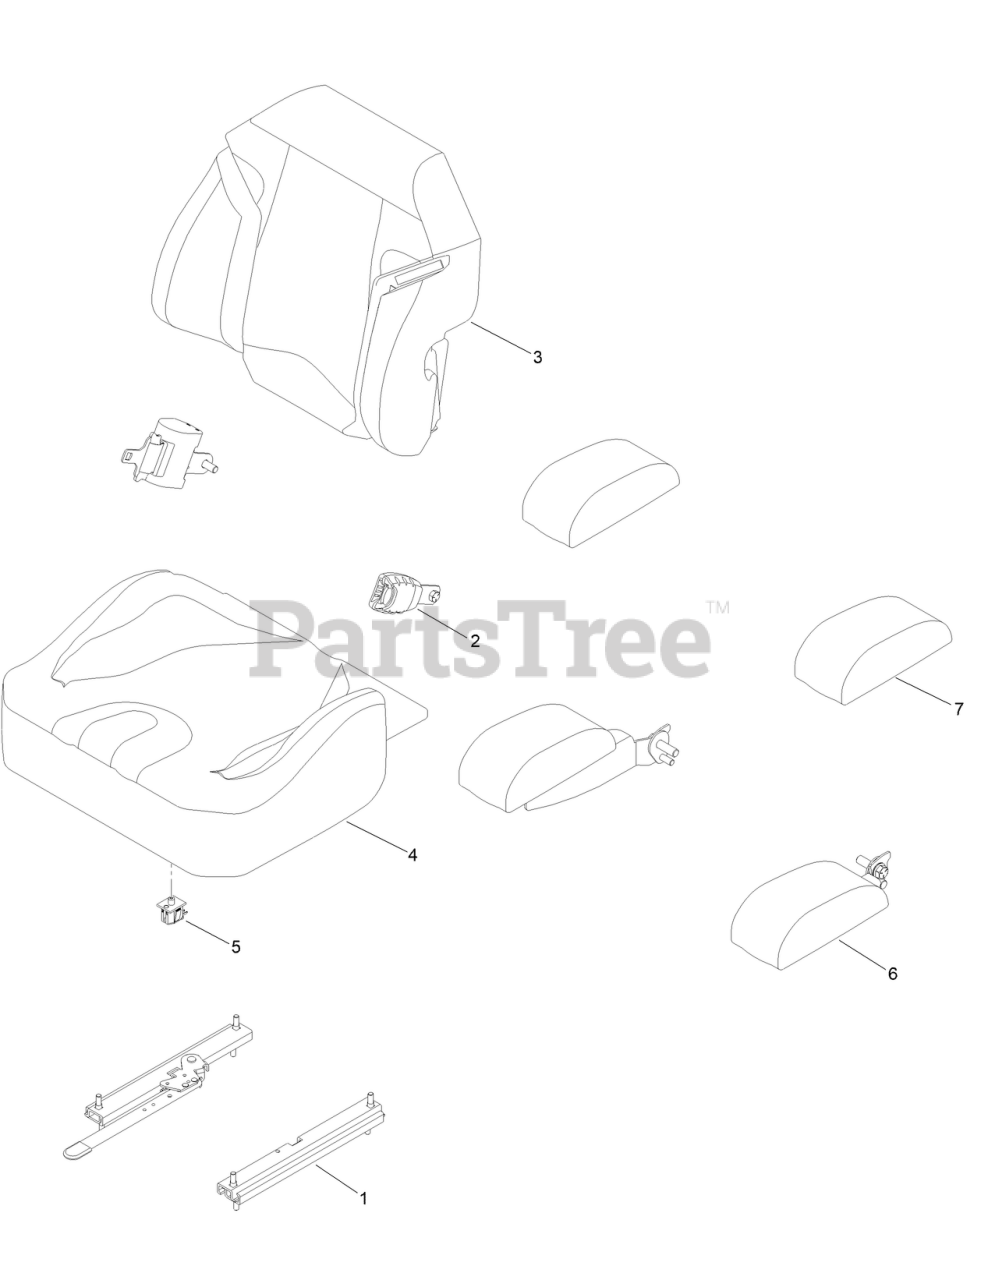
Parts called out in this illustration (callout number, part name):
1	SEAT TRACK KIT
2	SEAT BELT KIT
3	COVER-BACK, SEAT
4	COVER-BOTTOM, SEAT
5	SWITCH-SEAT
6	ARM REST KIT
7	PADS-ARMREST W/ HARDWARE
